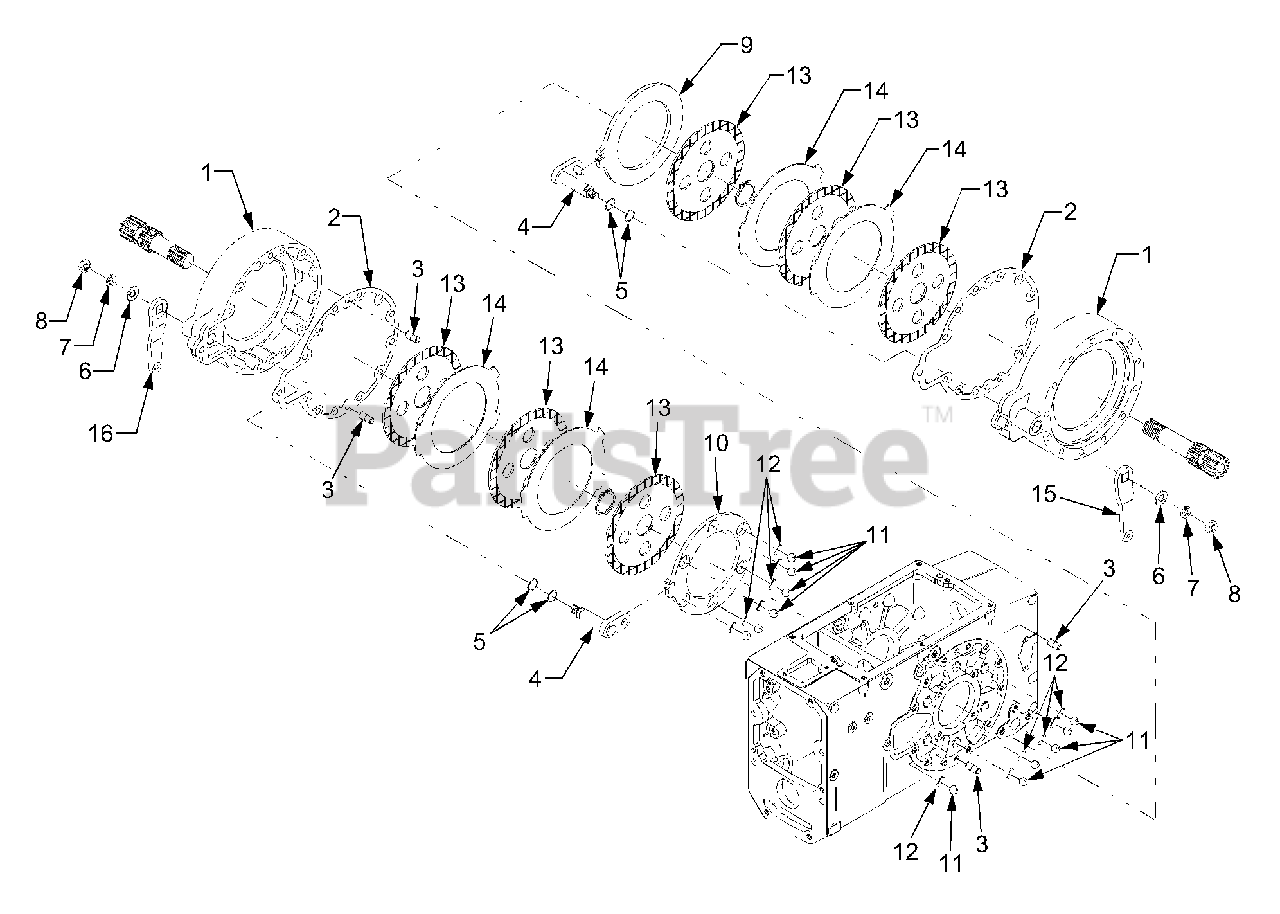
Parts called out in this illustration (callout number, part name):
3	Pin, Straight
6	Washer, Plain
7	Washer, Spring
9	Plate, Cam (RH)
10	Plate, Cam (LH)
15	Lever, Brake (LH)
16	Lever, Brake (RH)
